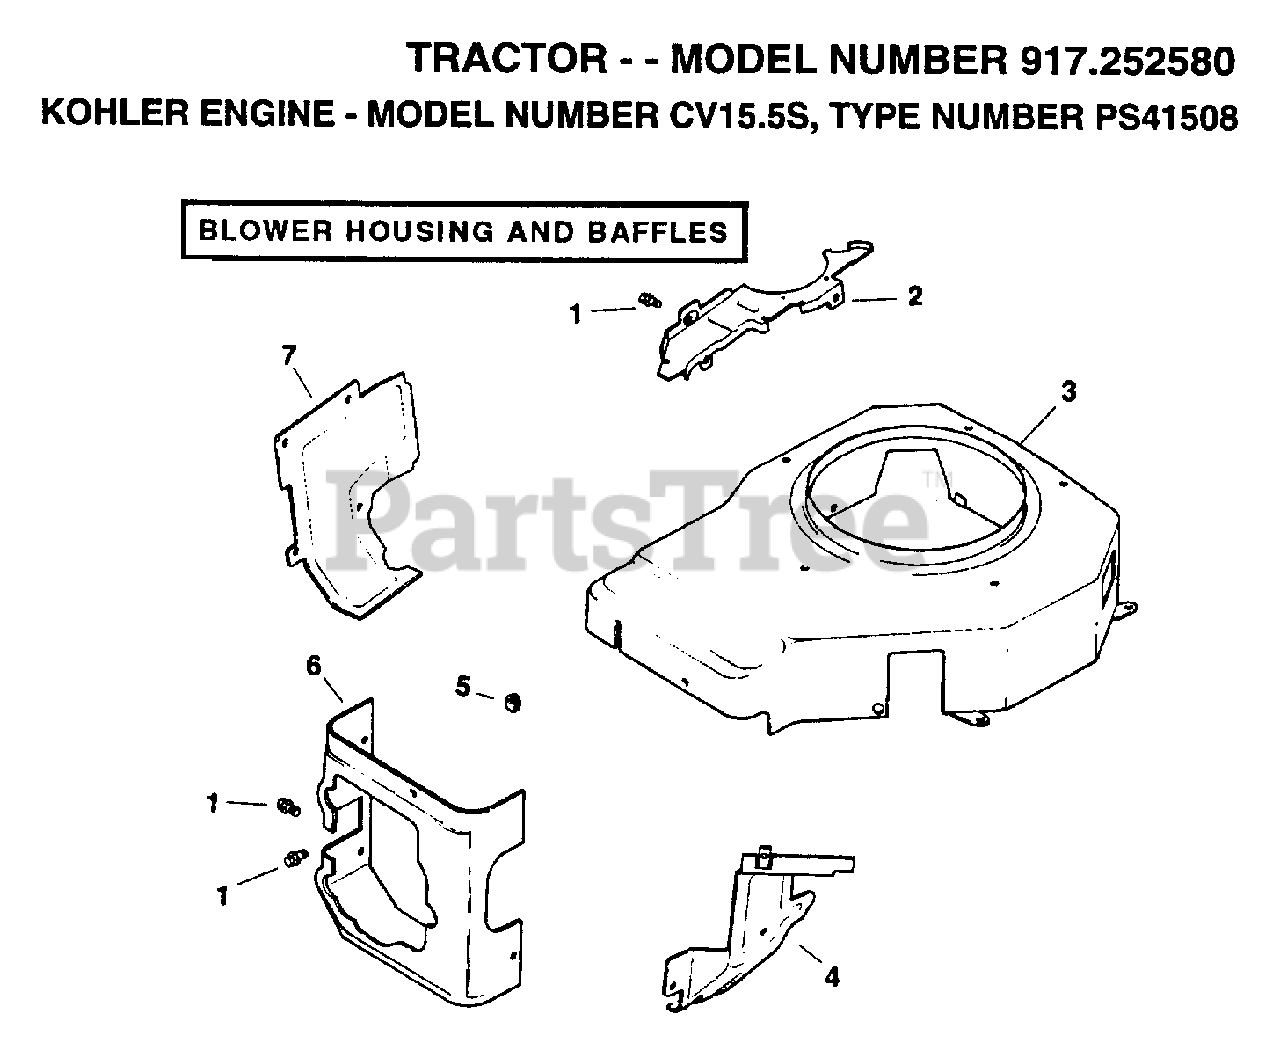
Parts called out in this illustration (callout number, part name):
1	SCREW, MOUNTING
2	PLATE, BLOWER HOUSING
3	HOUSING, BLOWER
4	BAFFLE, CARBURETOR
5	GROMMET, BLOWER HOUSING
6	BAFFLE, CYLINDER HEAD
7	BAFFLE, CYLINDER
